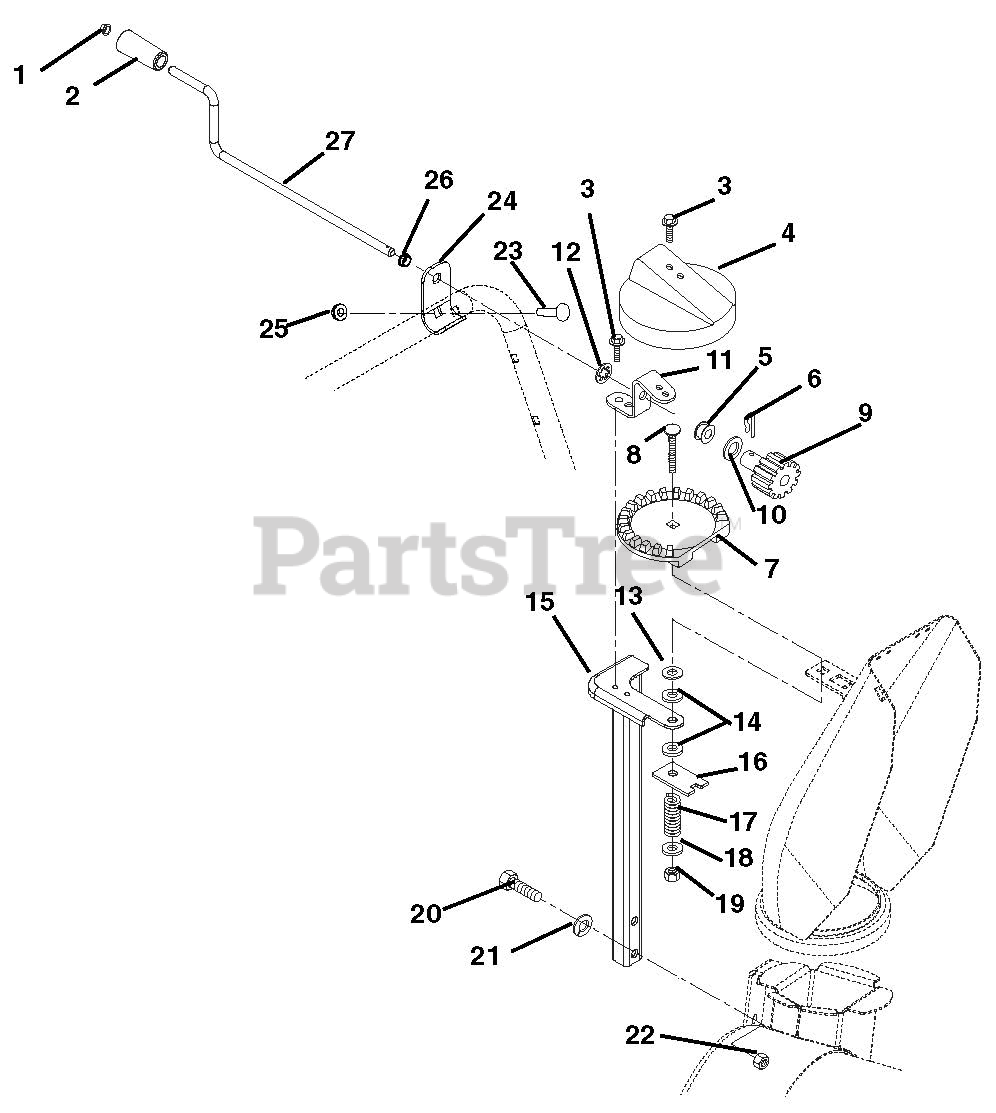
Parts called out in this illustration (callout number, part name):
1	CAP, 3/8 ROD YWZC
2	KNOB, CHUTE CRANK
3	@SCR-TAP .25-20X.50 HWH TR YWZ
4	GEAR COVER
5	BUSHING, POLYLINER-.63 SNAPIN
6	PIN, SPRING CLIP
7	CHUTE GEAR
8	@BLT-RDHDSQNK .38-16X2.50 G5YZ
9	PINION GEAR W/BRACKET
10	WSHR-THRST .625 X 1.0 X .03
11	BRACKET, PINION GEAR
12	PUSHNUT .625
13	WSHR-FL-STL .380X1.50X.062 YWZ
14	FRICTION WASHER
15	WELDMENT, CHUTE PEDESTAL
16	PLATE, FRICTION
17	SG-COMP .187X.56X1.62
18	@WSHR-FL-STL.406X.812X.065 YWZ
19	@NUT-LK-CTR .38-16 YWZC
20	@BLT-HEX .38-16X1.75 GR5 YWZC
21	@WSHR-LK .38X.094 REG YWZC
22	@NUT-LK-TOP-FLG .38-16 YWZC
23	@BLT-RDHDSQNK .31-18X1.50 G5YZ
24	BRACKET, CRANK SUPPORT
25	@NUT-LK-TOP-FLG .31-18 YWZC
26	BUSHING, POLYLINER-.38 SNAPIN
27	ROD, CHUTE CRANK
